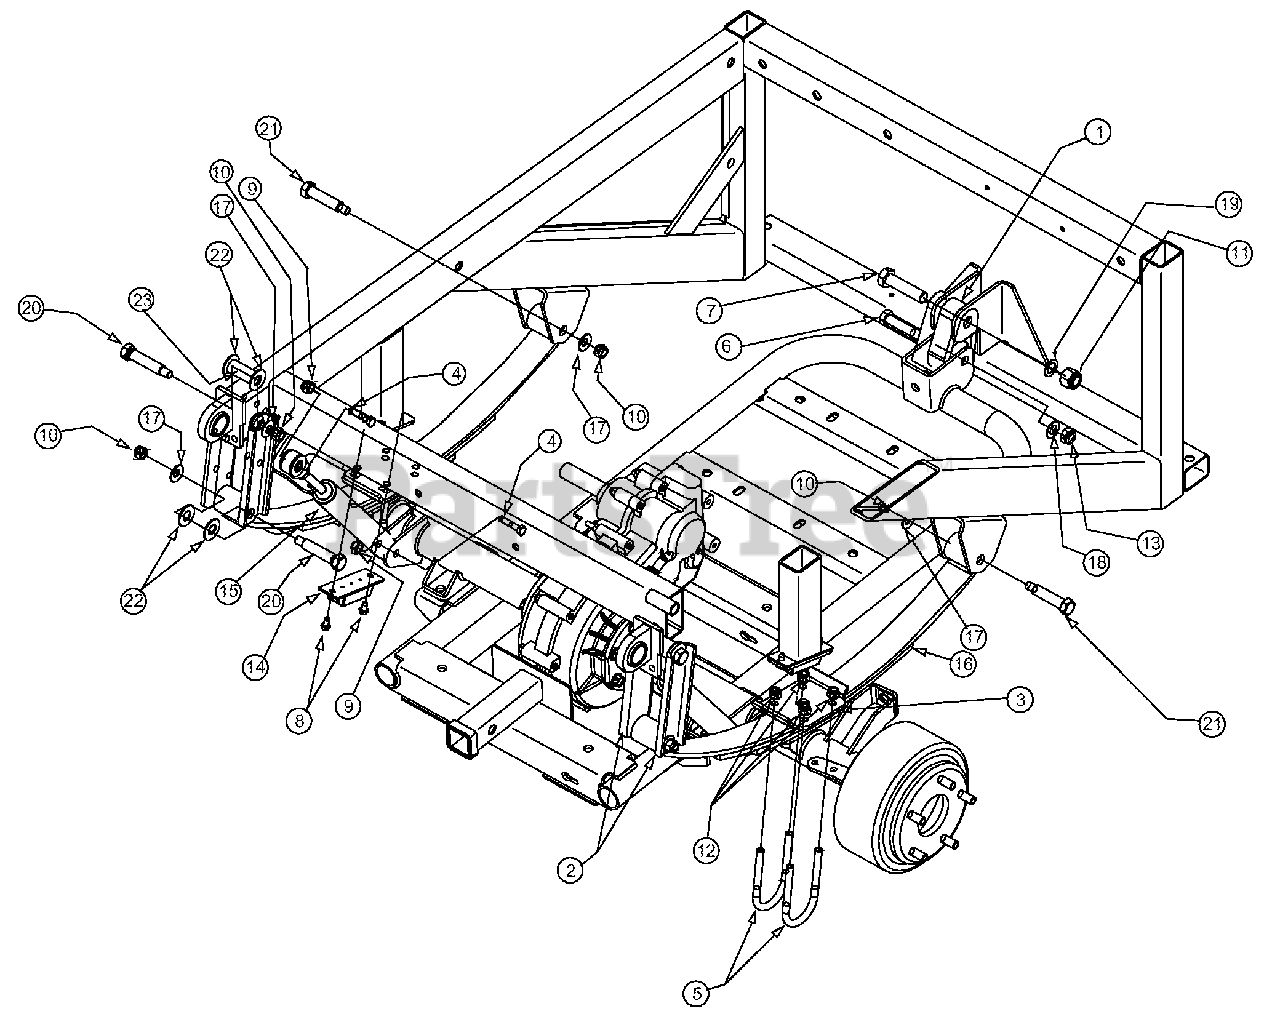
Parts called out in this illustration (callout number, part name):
1	Link Assembly
2	Plate, Shackle
3	Bracket, Spring Leaf
4	Hex Screw, M!)-1.25
5	U-Bolt 3/8-16
6	Hex Screw, M12-1.75
7	Hex Screw, 5/8-11 x 2.5
8	Screw, Self Tapping 1/4-20
9	Locknut, M10 x 1.25
10	Hexlock Nut
11	Hexlock Nut, 5/8 - 11
12	Hexlock Nut, 3/8-16
13	Hexlock Nut, M12 x 1.75
14	Bumper, Suspension
15	Shock Absorber, 2.50 Stroke
16	Spring, Leaf 4 x 2
17	Bell Washer, .45 x 1.00 x .062
18	Flat Washer, .510 x 1.00 x .060
19	Flat Washer, .632 x 1.00 x .035
20	Shoulder Screw, .550 x 2.290
21	Shoulder Screw, .550 x 2.13
22	Bearing, .56 ID x 1.25 OD x .06
23	Bushing, .75 OD x .562 ID x 1.75 LG
